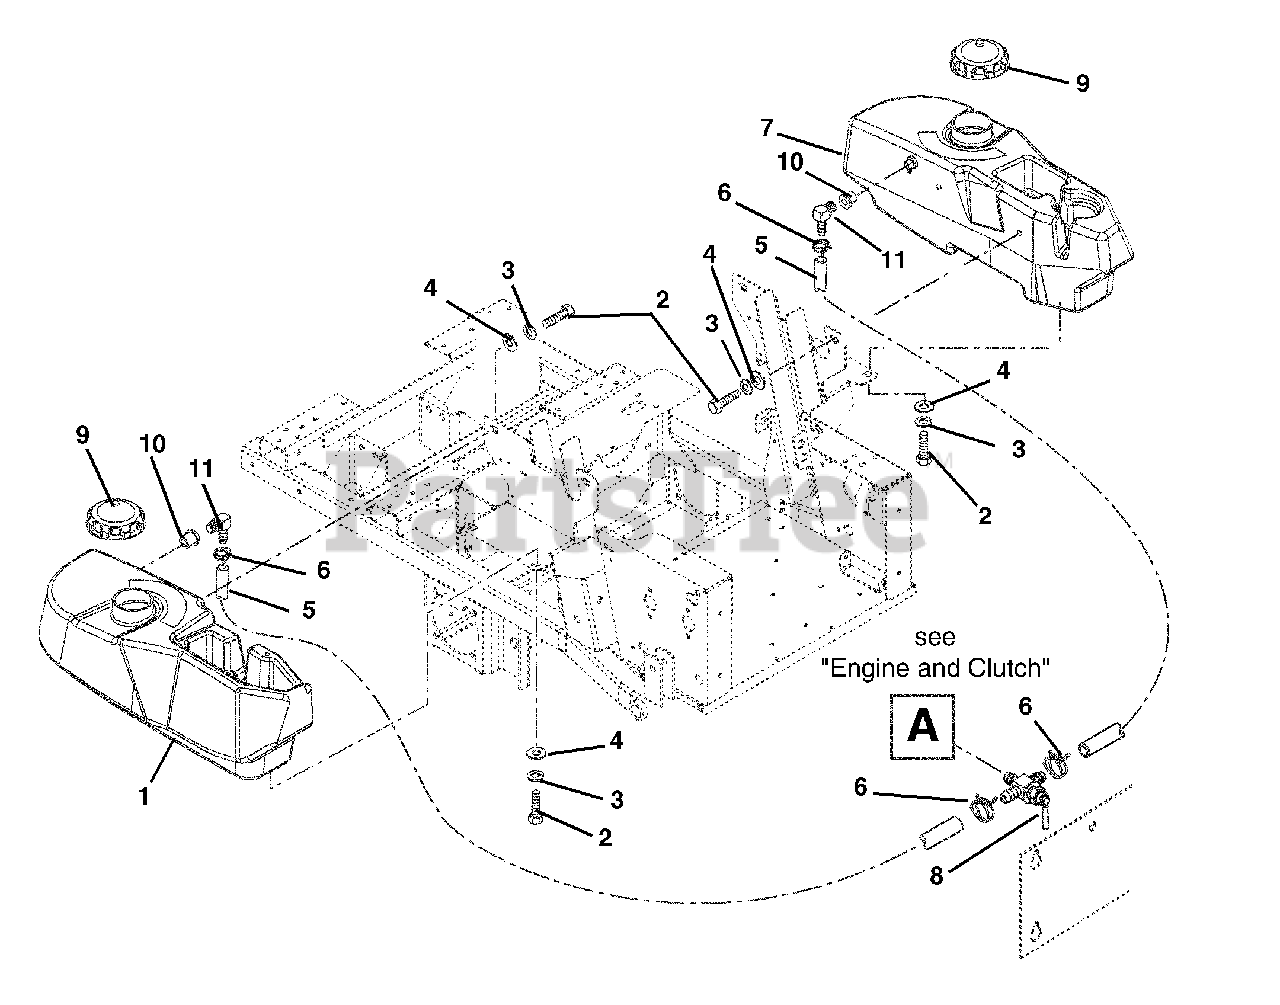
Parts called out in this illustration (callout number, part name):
1	Tank, Gas Fuel Right Hand
2	Bolt-Hex .31-18 x .75 Grade 5
3	Washer-Locking .31 x .078
4	Washer-Flat-Steel .38 x .875 x .083
5	Gas Line-Bulk .25 I.D.
6	Clamp-Hose Wire .49/.51 x .116
7	Tank, Gas Fuel Left Hand
8	Valve, Fuel
9	Cap-Gas
11	Tank Fitting
